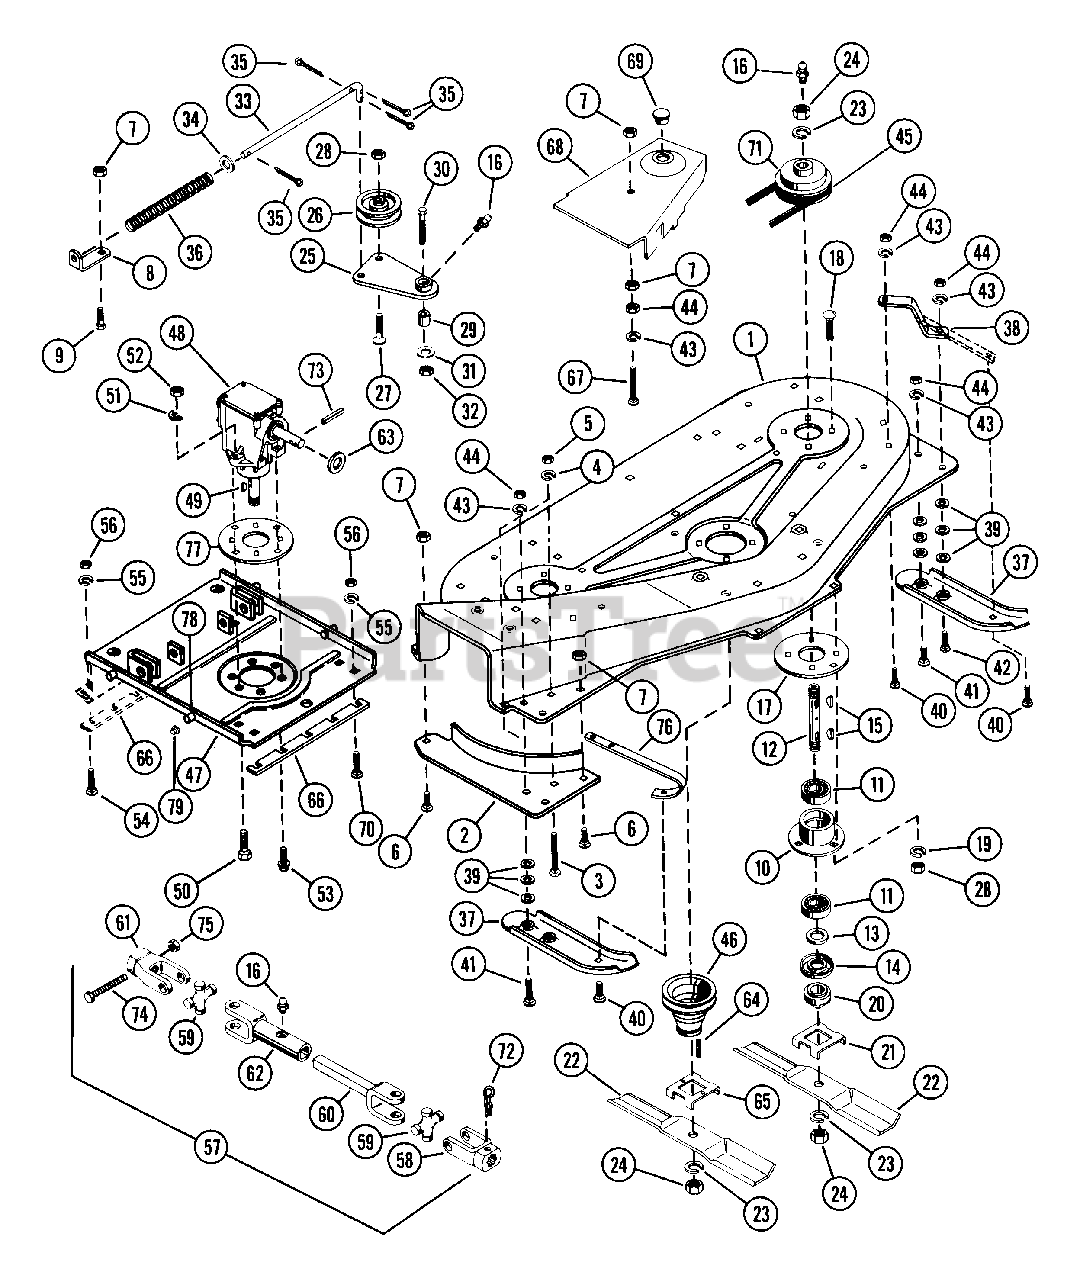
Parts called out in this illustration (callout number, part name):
1	48 INCH MOWER PAN W/DECALS
2	TOE GUARD
3	BLT-RDHDSQNK .38-16X2.00 SHTYW
4	WSHR-LK .375X.115 HVY PL
5	NUT-HEX .375-16
6	BLT-RDHDSQNK .312-18X.62 PL
7	NUT-LK .312-18 GR A PL
8	BRACKET
9	BLT-HEX .31-18X.50 GR5
10	HOUSING, SPINDLE
11	BRG-BALL .750X1.781X.61
12	SPINDLE SHAFT W/ZERK
13	WSHR-FL-STL .754X1.000X.032
14	BEARING SLINGER
15	KEY-WDRF .188X.625X.25 SAE 61
16	SPIN DRIVE ZERK FITTING
18	BLT-RDHDSQNK .38-16X1.0 GR5PL
19	WSHR-LK .375X.094 MED PL
20	RETAINER HUB
21	BLADE TRAY
23	WSHR-LK .750X.188 MED PL
24	NUT-JAM .75-10 PL
25	IDLER ARM W/ZERK
26	IDLER-FLAT 4.00 X .38 NWHAMSHR
27	BLT-BTHD .38-16X1.25 GR5
28	NUT-LK-JAM-CTR .375-16 PL
29	SPACER .512X.747X.968
30	BLT-HEX .50-13X1.50 PL GR2
31	WSHR-FL-STL .505X.880X.072 PL
32	NUT-LK-CTR .50-13
33	ROD-IDLER SPRING
34	WSHR-FL-STL.406X.812X.065PL
35	PIN-COTR .09X.75 PL
36	SG-COMP .106X.63X 12.0 WLD 62
37	SKID
38	BRACE
39	WSHR-FL-STL .38X.875X.083 PL
40	BLT-RDHDSQNK .31-18X.75 GR5 PL
41	BLT-RDHDSQNK .31-18X1.00 PL
42	BLT-RDHDSQNK .31-18X1.25 SHTPL
43	WSHR-LK .312X.097 PL HVY
44	NUT-HEX .312-18
45	V-BELT, HA-WRAPPED
47	MOUNTING PLATE
48	MOWER GEAR CASE OLD 48" & 60"
49	KEY-WDRF .25X.750X.313 SAE91
50	BLT-HEX .31-18X1.25 PL GR5
52	NUT-LK-TOP .312-18 GR C PL
53	SCR-TAP .312-18X1.0 THH PL TR
54	BLT-RDHDSQNK .50-13X1.25GR5PL
55	WSHR-LK .500X.151 HVY PL
56	NUT .50-13 PL
57	PTO ASSEMBLY
59	JOURNAL CROSS & BEARING ASSEMB
60	YOKE AND SHAFT
60	YOKE & SHAFT
62	SLIP YOKE
63	WSHR-FL-STL .754X1.000X.032
64	PIN-GRV .188X.75 TP A
65	BLADE TRAY
67	BLT-RDHDSQNK .31-18X3.0 SHT PL
68	BELT COVER-RH
68	BELT COVER LH
69	BUTTON PLUG 1.0
70	BLT-RDHDSQNK .50-13X1.50 PL
72	PIN-HAIR INT .18X1.18X3.25 PL
73	PIN-ROLL .125X1.00
74	BLT-HEX .25-20X2.13 GR5
75	NUT-LK TOP .250-20 PL
78	RVT .312X.75 RH ST
79	NUT-PUSH .312
